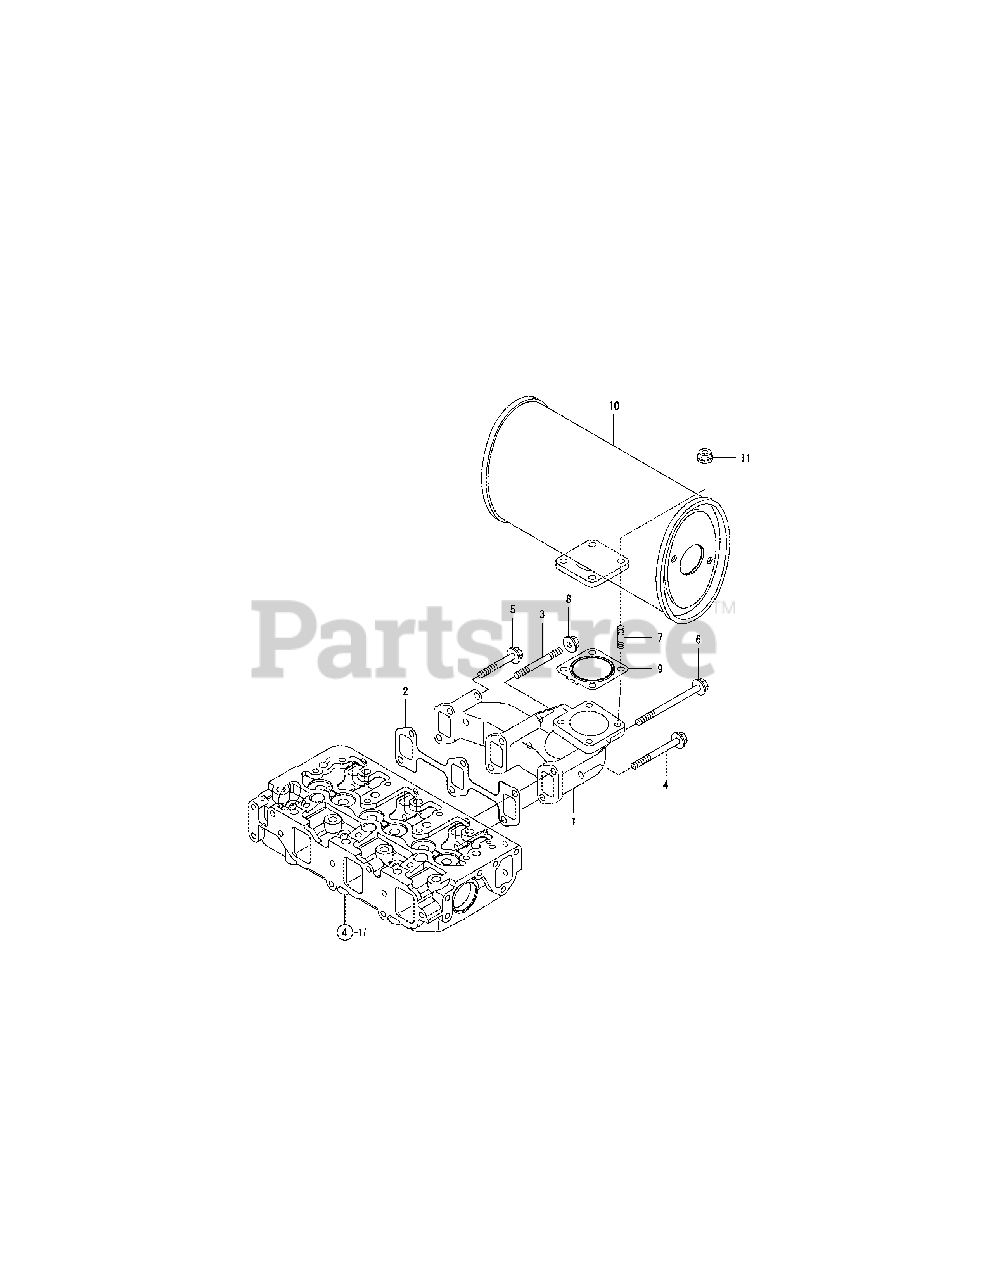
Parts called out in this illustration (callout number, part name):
1	MANIFOLD, EXHAUST
2	GASKET, EXH.MANIFOLD
3	STUD BOLT M 8X 80
9	GASKET, SILENCER
